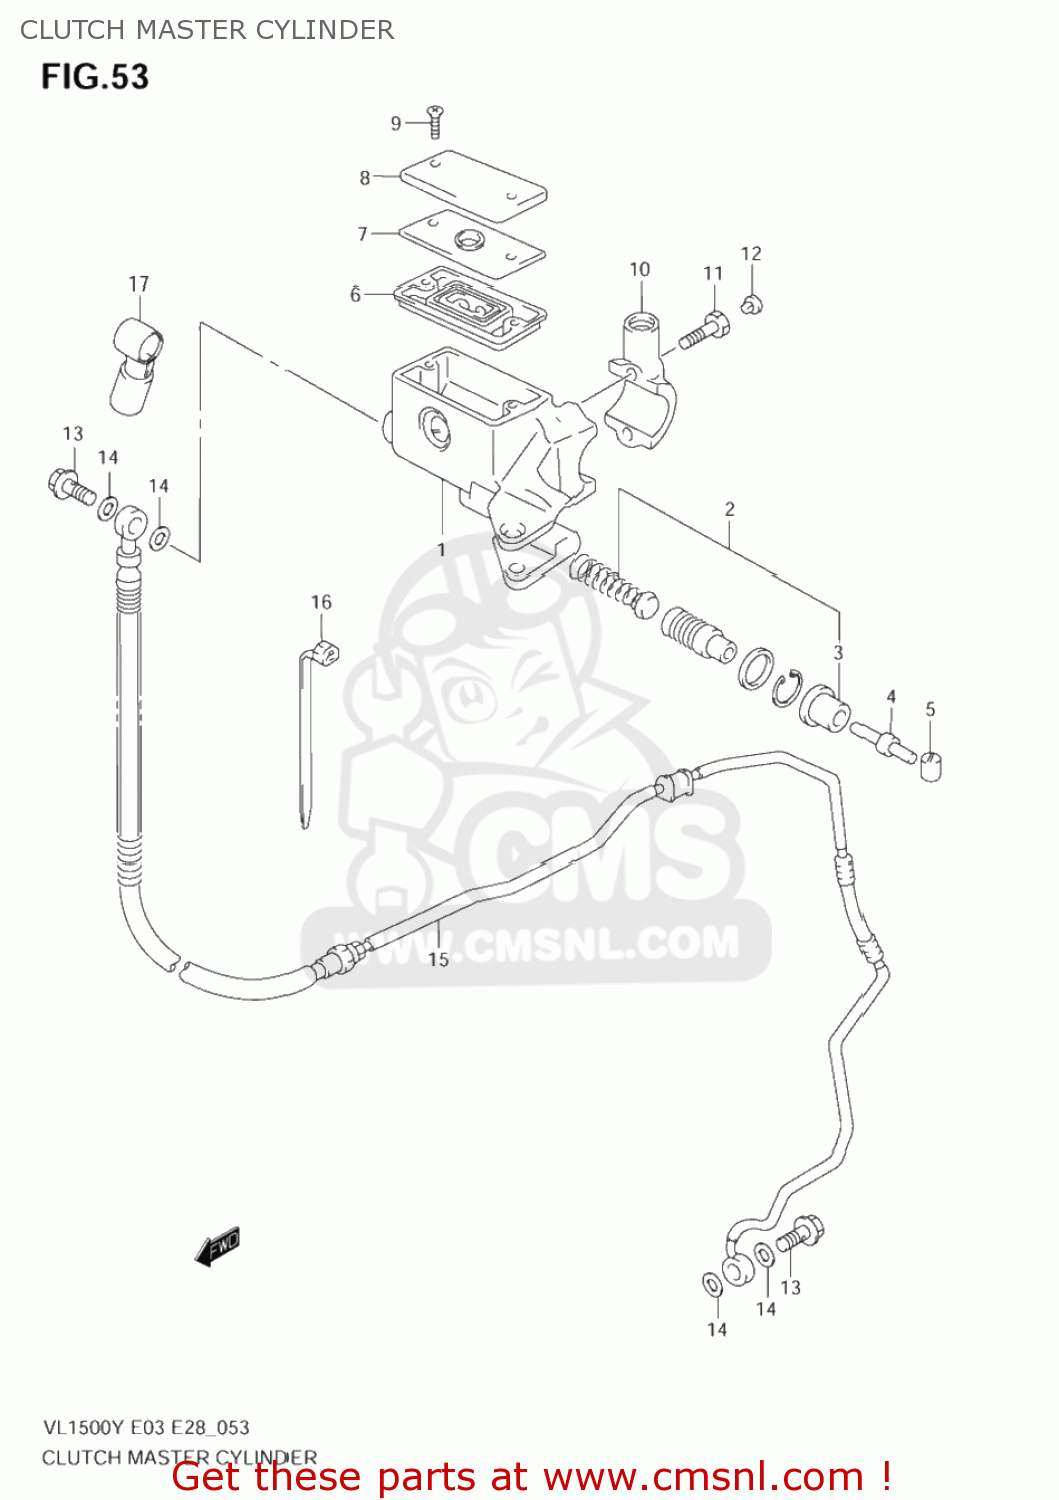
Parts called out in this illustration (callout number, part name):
1	CYLINDER ASSY,CLUTCH MASTER
2	PISTON & CUP SET
3	BOOT
4	ROD,PUSH
5	BUSH
6	7
7	PLATE,DIAPHRAGM
8	CAP
9	SCREW
10	HOLDER
11	BOLT
12	CAP(OD:10)
13	BOLT UNION
14	WASHER(10X15X1.5)
15	HOSE ASSY,CLUTCH
16	CLAMP(L:235)
17	BOOT,CLUTCH MASTER CYLINDER
